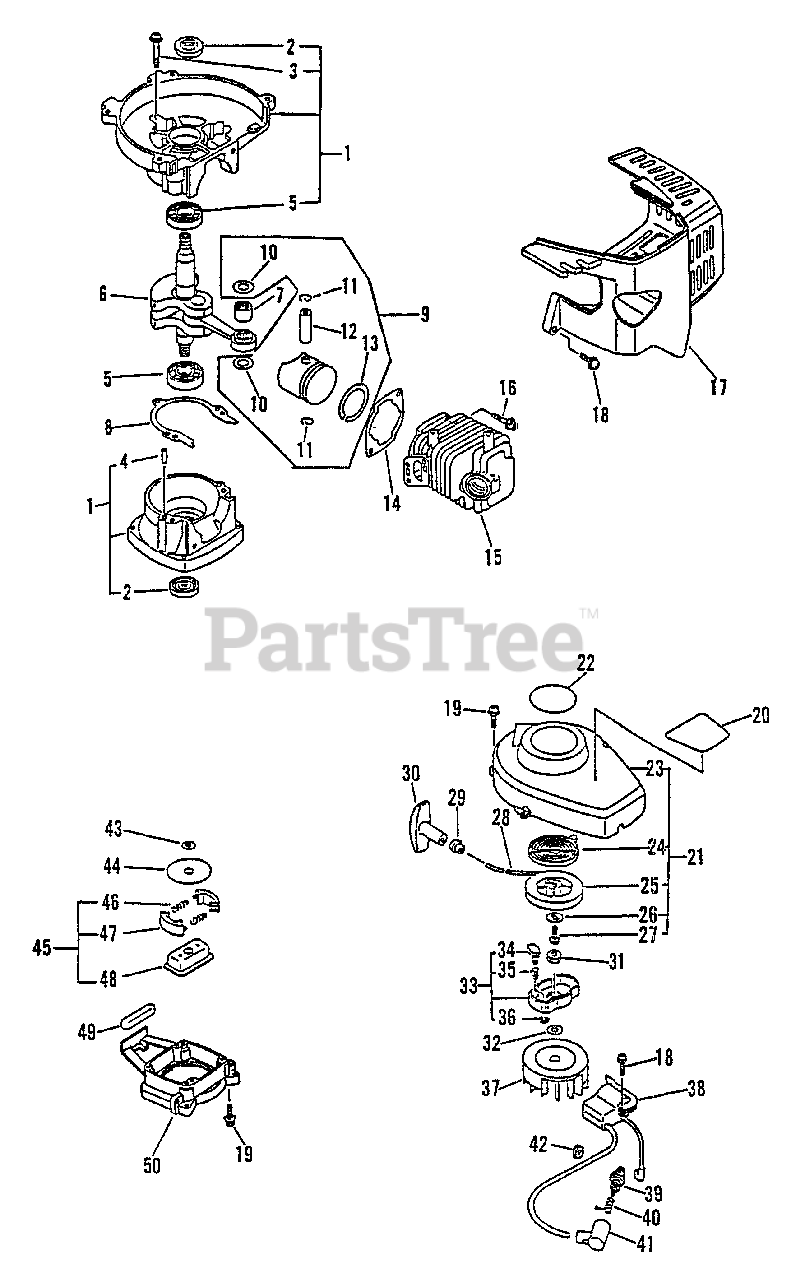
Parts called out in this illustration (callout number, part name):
1	CRANKCASE KIT
2	SEAL, OIL 12
3	SCREW 5×28
4	PIN, LOCATING 4
5	BEARING, BALL - 6201 C3
6	CRANKSHAFT ASSY
7	BEARING, NEEDLE
8	GASKET, CRANKCASE
9	PISTON KIT
10	WASHER, THRUST
11	RING, SNAP
12	PIN, PISTON 8
13	RING, PISTON
14	GASKET, CYLINDER
16	BOLT 5×22
17	COVER, ENGINE
18	SCREW 4×22
19	SCREW 4×16
20	LABEL, LHS-3000
21	STARTER ASSY
23	CASE, STARTER
24	SPRING, RECOIL
25	REEL, ROPE
26	WASHER
27	SCREW
29	GUIDE, ROPE
30	GRIP, STARTER
32	WASHER 8.5×16×1.2
33	STARTER PAWL ASSY
34	PAWL, STARTER
35	SPRING, RETURN
36	E-RING 4
37	FLYWHEEL
38	COIL, IGNITION
39	SPARK PLUG - BPM7A
40	TERMINAL, SPARK PLUG
41	CAP, SPARK PLUG
43	WASHER, CLUTCH
44	PLATE, CLUTCH
45	CLUTCH ASSY
46	SPRING, CLUTCH
47	SHOE, CLUTCH
48	HUB, CLUTCH
49	CUSHION, FUEL TANK
50	CASE, CLUTCH
